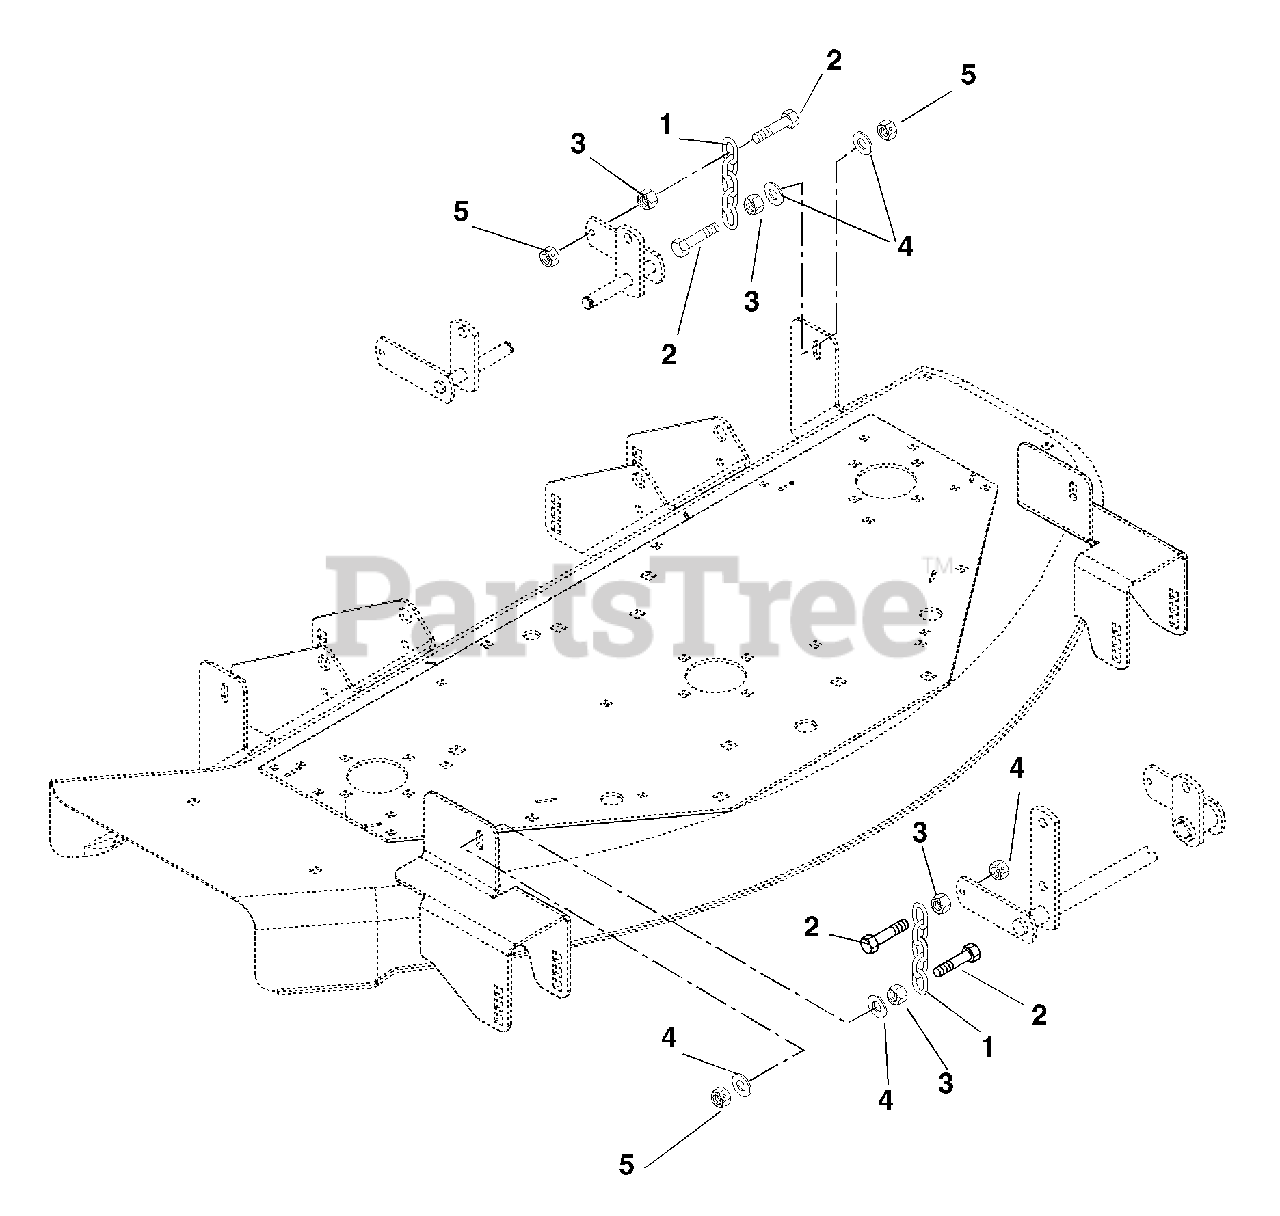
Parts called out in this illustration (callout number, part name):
1	Chain, Link
2	Bolt-Hex .38-16 x 1.50 Grade 5
3	Nut-Hex .38-16
4	Washer-Flat-Steel .406 x .812 x .065
5	Nut-Locking-Center .38-16
